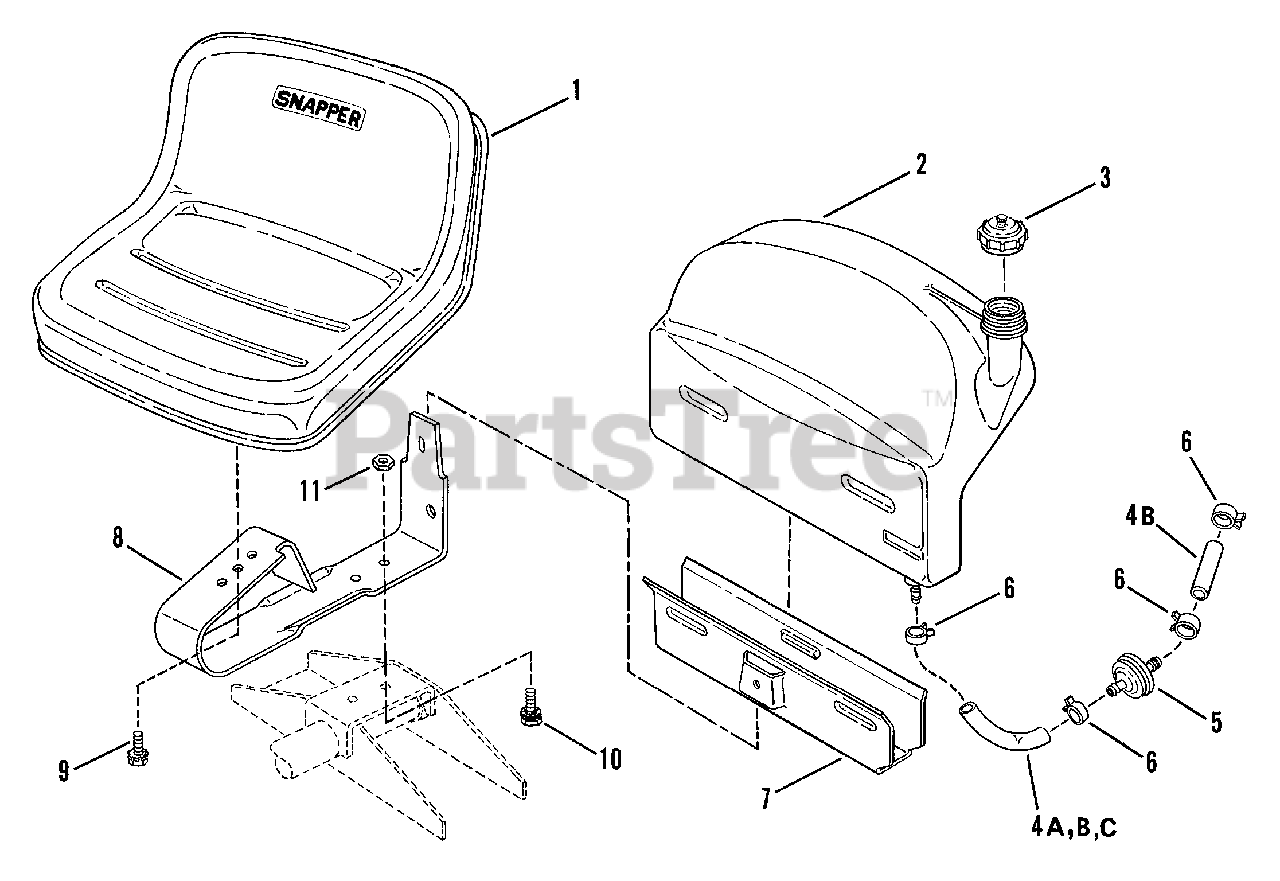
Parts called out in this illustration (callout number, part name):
1	SEAT, Operator (19" Wide, 9" High, 17" Long)
2	ASSEMBLY, Fuel Tank
3	CAP, Fuel Tank
4A	HOSE, Fuel (7" Long) (Briggs Engine)
4B	HOSE, Fuel, 3" (Robin Engine)
4C	HOSE, Fuel 3" (Tecumseh Engine)
5	FILTER, Fuel (In-Line)
6	CLAMP, Fuel Line
7	BRACKET, Fuel Tank
8	SPRING, Operator's Seat
9	BOLT, 1/2-13 x 3/4" Hex Flange Lock
10	BOLT, 3/8-16 x 1" Hex Flange lock
11	NUT, 3/8 Hex Flange Lock
